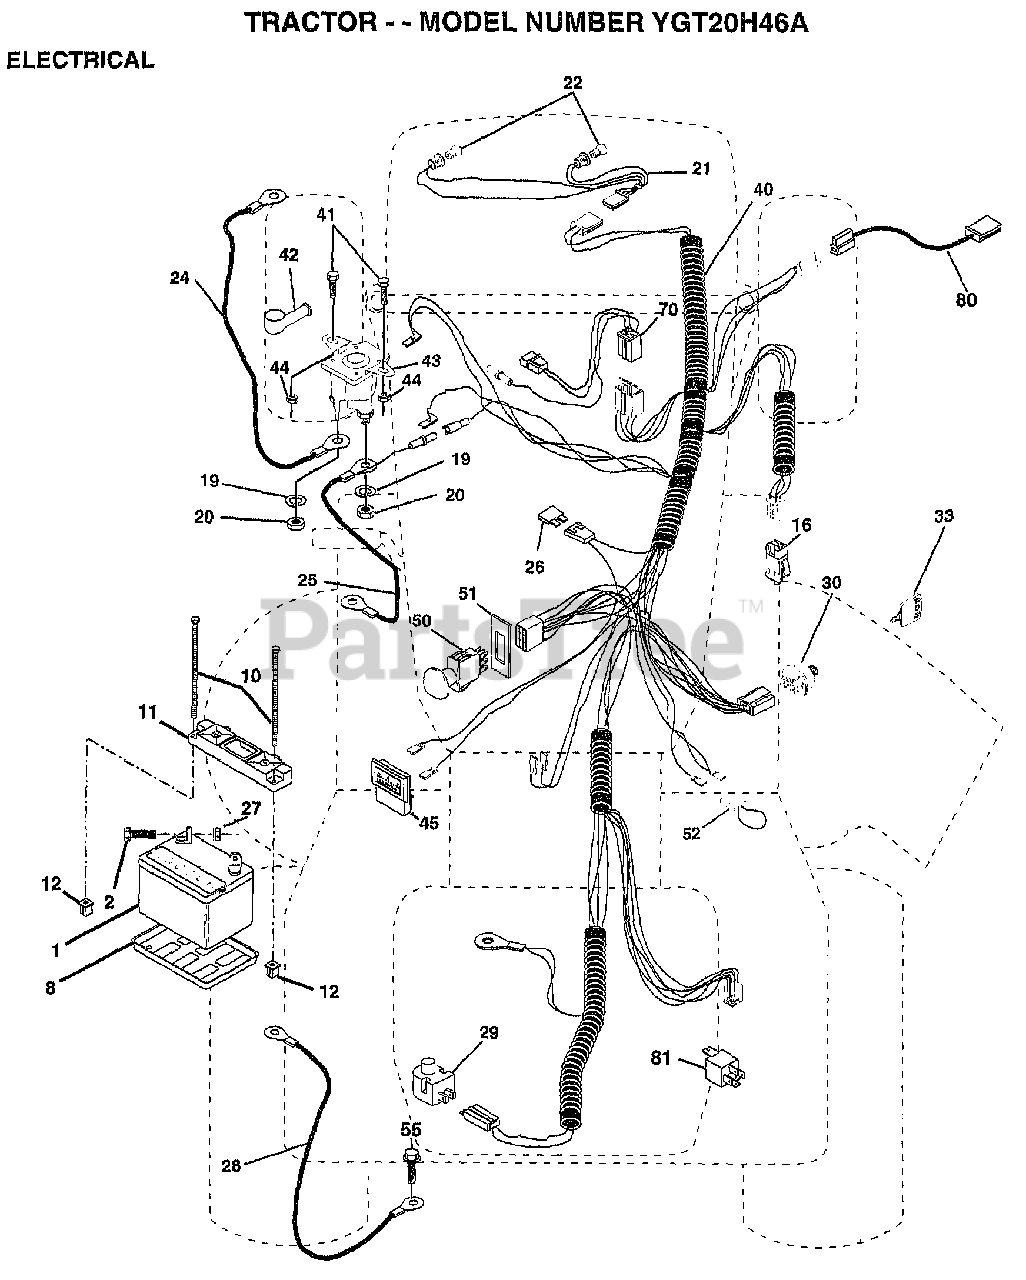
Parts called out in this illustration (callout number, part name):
2	BOLT LT
8	"TRAY T, BATTERY"
11	HOLDDOWN BATTERY
16	SWITCH INTERLOCK
20	NUT
21	HARNESS.ASM.LIGHT.W/4152J
22	HEADLAMP BULB
24	CABLE-BATTERY T
25	CABLE.6GA.22W/16W
26	FUSE.15 AMP
27	NUT
28	CABLE.GRND.6GA.21
29	SWITCH.PLUNGER
30	SWITCH.IGN.
33	KEY MLD GEN DELTA
40	HARNESS
41	BOLT HXHD FIN
44	NUT HXKEP 1/4X20
45	AMMETER
50	PTO SWITCH.BLK
51	RING RETAIN PTO
52	PROTECTION LOOP
55	SCREW LT
70	HARNESS.ENGINE
80	HARNESS.CLUT.EVX.
81	RELAY ASSY T
